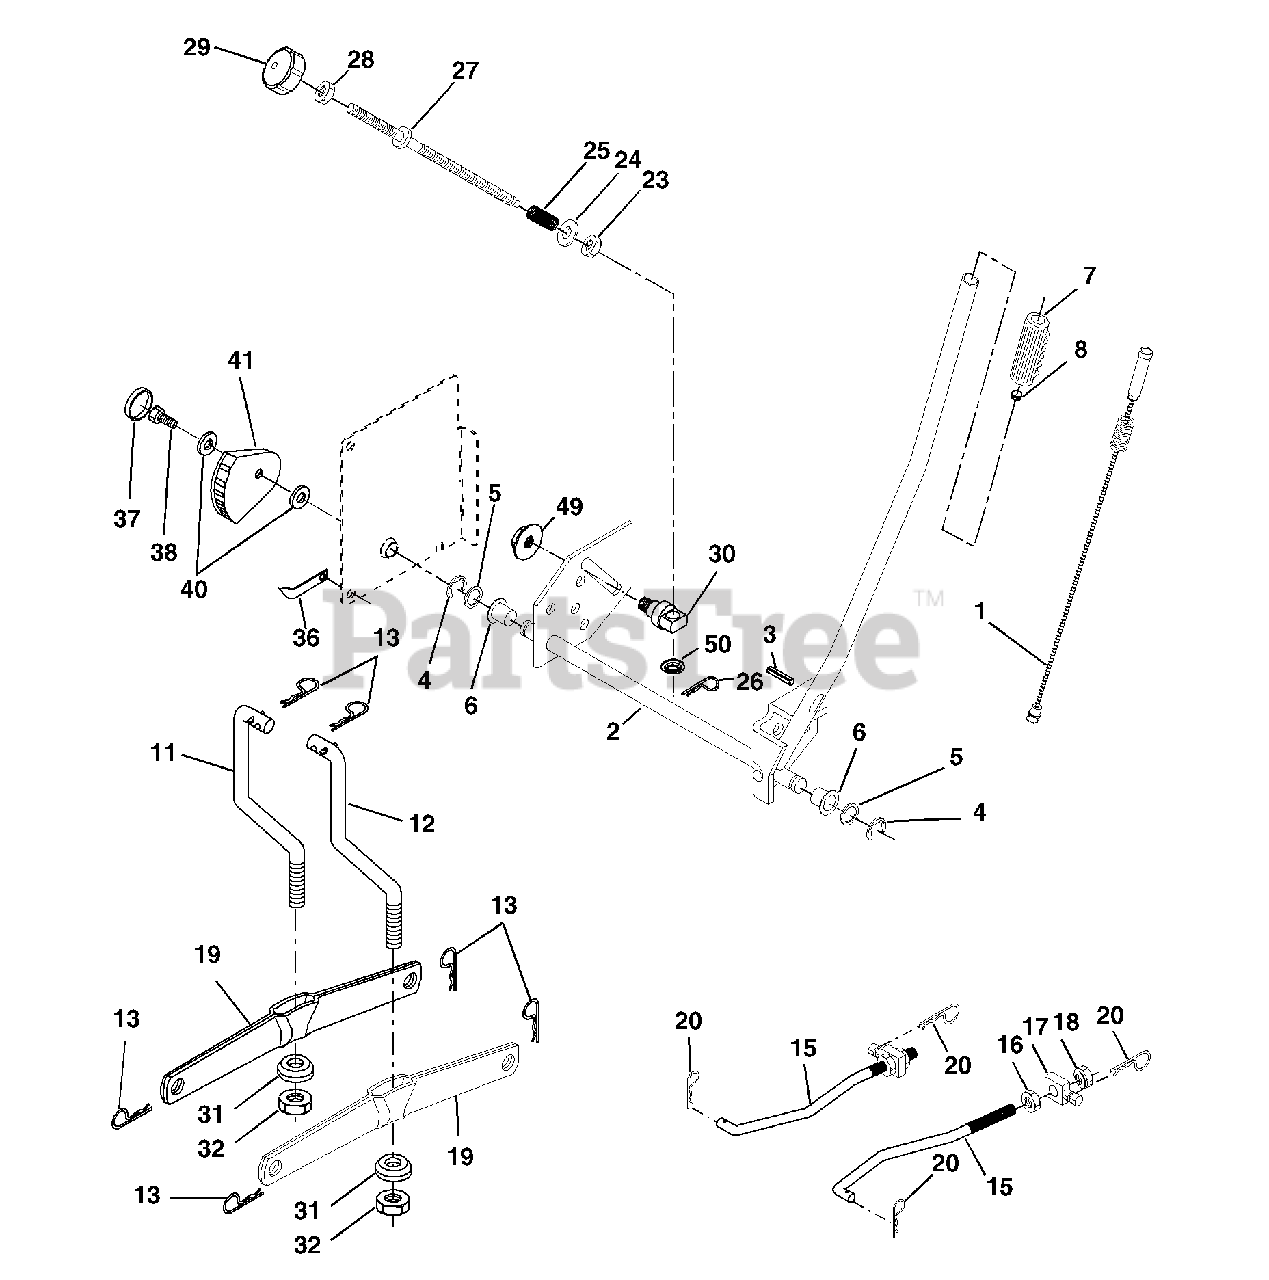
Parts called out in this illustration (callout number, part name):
1	Wire Asm Inner W/plunger
2	Shaft Asm Lift RH w/Inf
3	Pin Groove 1 500 Zinc
4	E Ring #5133-62
5	Washer 21/32 X 1 X 21 Ga
6	Bearing Nylon Blk 629 Id
7	Grip Handle Fluted Blk
8	Button Plunger Black
11	Link Lift LH Fixed Length
12	Link Lift RH Fixed Length
13	Retainer Spring
15	Link Front
16	Nut Jam Hex 1/2-13 Unc
17	Trunnion Blk Zinc
18	Nut Lock w/Wsh 1/2-13unc
19	Arm Suspension Rear
20	Retainer Spring
23	Nut Special
24	Washer 13/32 X 5/8 X 16 Ga
25	Spring 2-1/8"
26	Retainer Clip
27	Rod Adj Lift Zinc 7.49 Wrk Lg
28	Nut Hex Jam 3/8-16 Unc
29	Knob Inf 3/8-16 Unc Blk W/sym
30	Trunnion Infin Height
31	Bearing Pvt Lift
32	Nut Crownlock 3/8 - 24
36	Pointer Height Indicator
37	Plug Hole Blk 1.485/1.515 Dia.
38	Screw 5/16-18 x 1
40	Washer 11/32 x 1-1/2 10 Ga.
41	Indicator Height STLT
49	Nut Hex Flange Lock
50	Nut Phos & Oil
